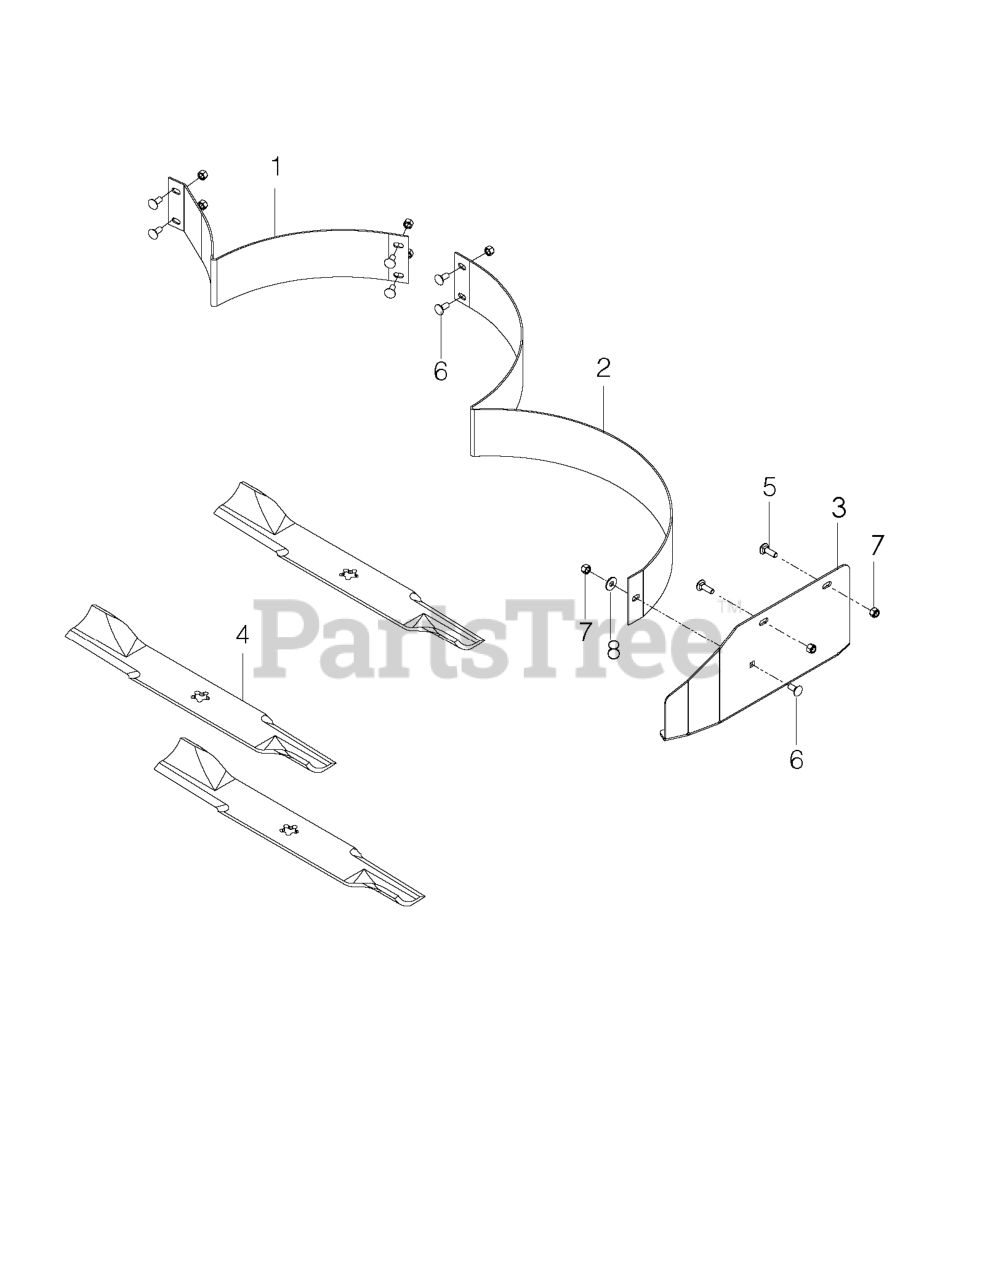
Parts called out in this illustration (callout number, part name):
1	61 MULCH BAFFLE - LH, BLACK
2	61 MULCH BAFFLE - RH, BLACK
3	61 MULCH CAP BLACK
4	BLADE, 21" GATOR
6	RP BOLT 5/16-18 X3/4 ZN/YEL GR
7	NUT.71038.31-18.HEX.NYLOCK
8	WASHER 5/16 FLAT
